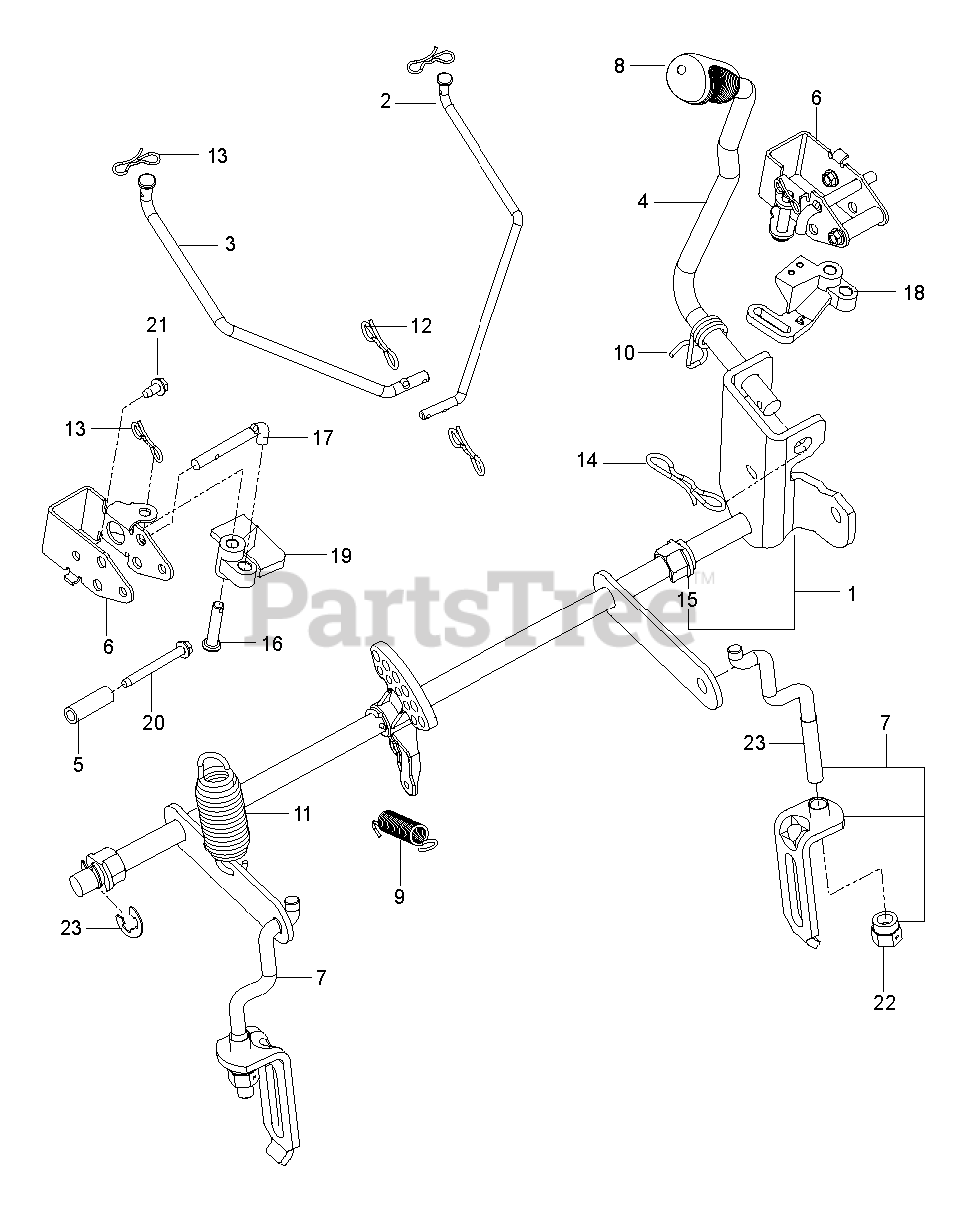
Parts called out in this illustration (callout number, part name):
1	SHAFT ASSY DECK LIFT WELDMENT
2	LINK.BRAKE.PARK.UPPER.LH
3	LINK.BRAKE.PARK.UPPER.RH
4	HANDLE LIFT ZTR
5	SPACER.334.ID.5.OD.1.5.L
6	BRACKET.BELLCRANK.PBRAKE X431
7	ASSEMBLY, BRKT LINK
8	GRIP.HANDLE.LIFT.PVC.428
9	RETURN.BRAKE.PARK.AUTO
10	SPRING.TORSION.LIFT.HANDLE
12	PIN COTTER;LOCKING;BOWTIE;1IN
13	PIN.COTTER.7/16.BOW TI.
14	PIN.COTTER.5/16.BOW TI
15	PLASTIC NUT
16	PIN.5.16X1.5
17	ROD.PUSH.BRAKE
18	BELLCRANK.LH
19	BELLCRANK.RH
20	SCREW THD;ROLL;1/4-20 X 2.25
21	SCREW.1/4-20X5/8
22	NUT, LIFT LINK 7/16-20
23	RETAINING RING LT
